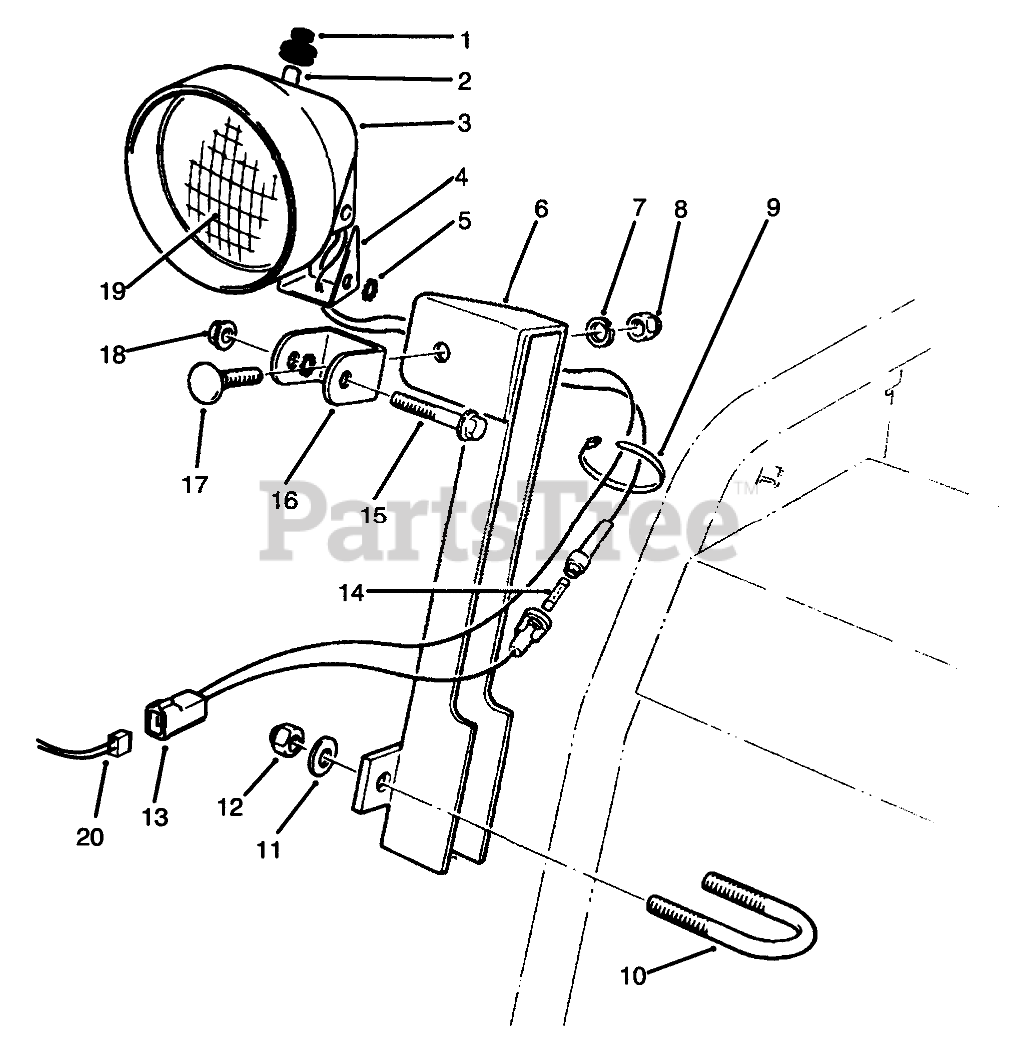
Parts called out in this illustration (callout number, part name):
1	BOOT-SWITCH
2	SWITCH ASM
3	Bucket-Headlamp
4	TO BE DISCONTINED-NOT NEEDED ON PRODUCT
5	WASHER-LOCK
6	Mount-Lamp
7	WASHER-LOCK
8	NUT-HEX
9	TIE-CABLE
10	U-BOLT
11	WASHER-PLAIN
12	NUT-LOCK, NI
13	Wire Assembly
14	Fuse7-1/2 Amp.
15	SCREW-HH
16	BRACKET
17	BOLT-CARR
18	NUT-HF
19	BEAM-SEALED
20	WIRE ASM
